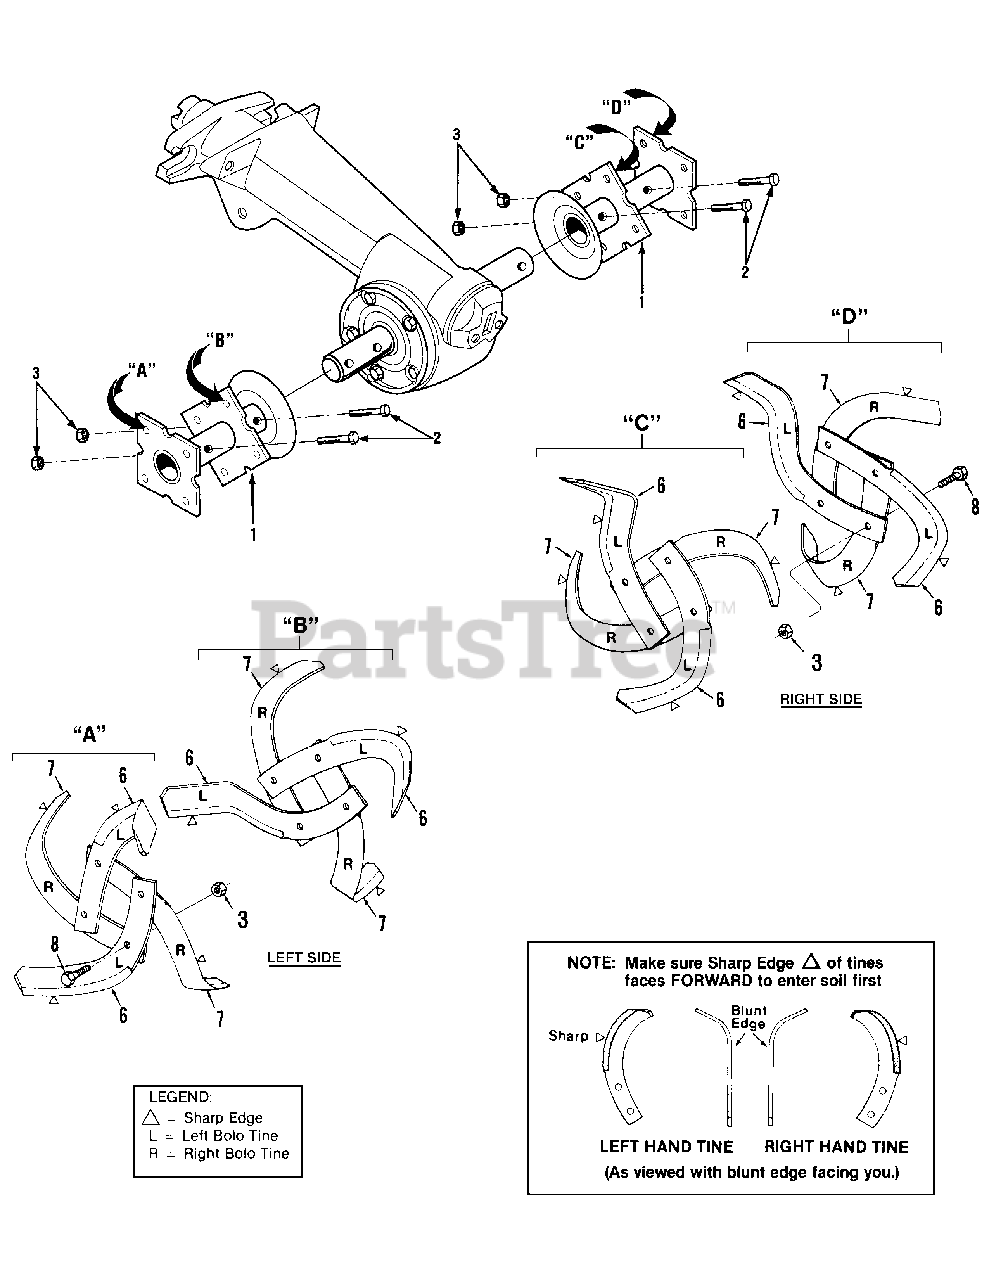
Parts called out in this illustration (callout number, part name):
1	Tine Holder-welded steel, fits or right sides (Standard Tilling Tines)
2	Bolt-hex hd., 3/8-16 x 2
3	Locknut-hex, 3/8"-16
6	Bolo Tine-single, Tine is stamped either "EL" or "AL"
7	Bolo Tine-single, Tine is stamped either "ER" or "AR"
8	Bolt-hex hd., 3/8-16 x 1"
